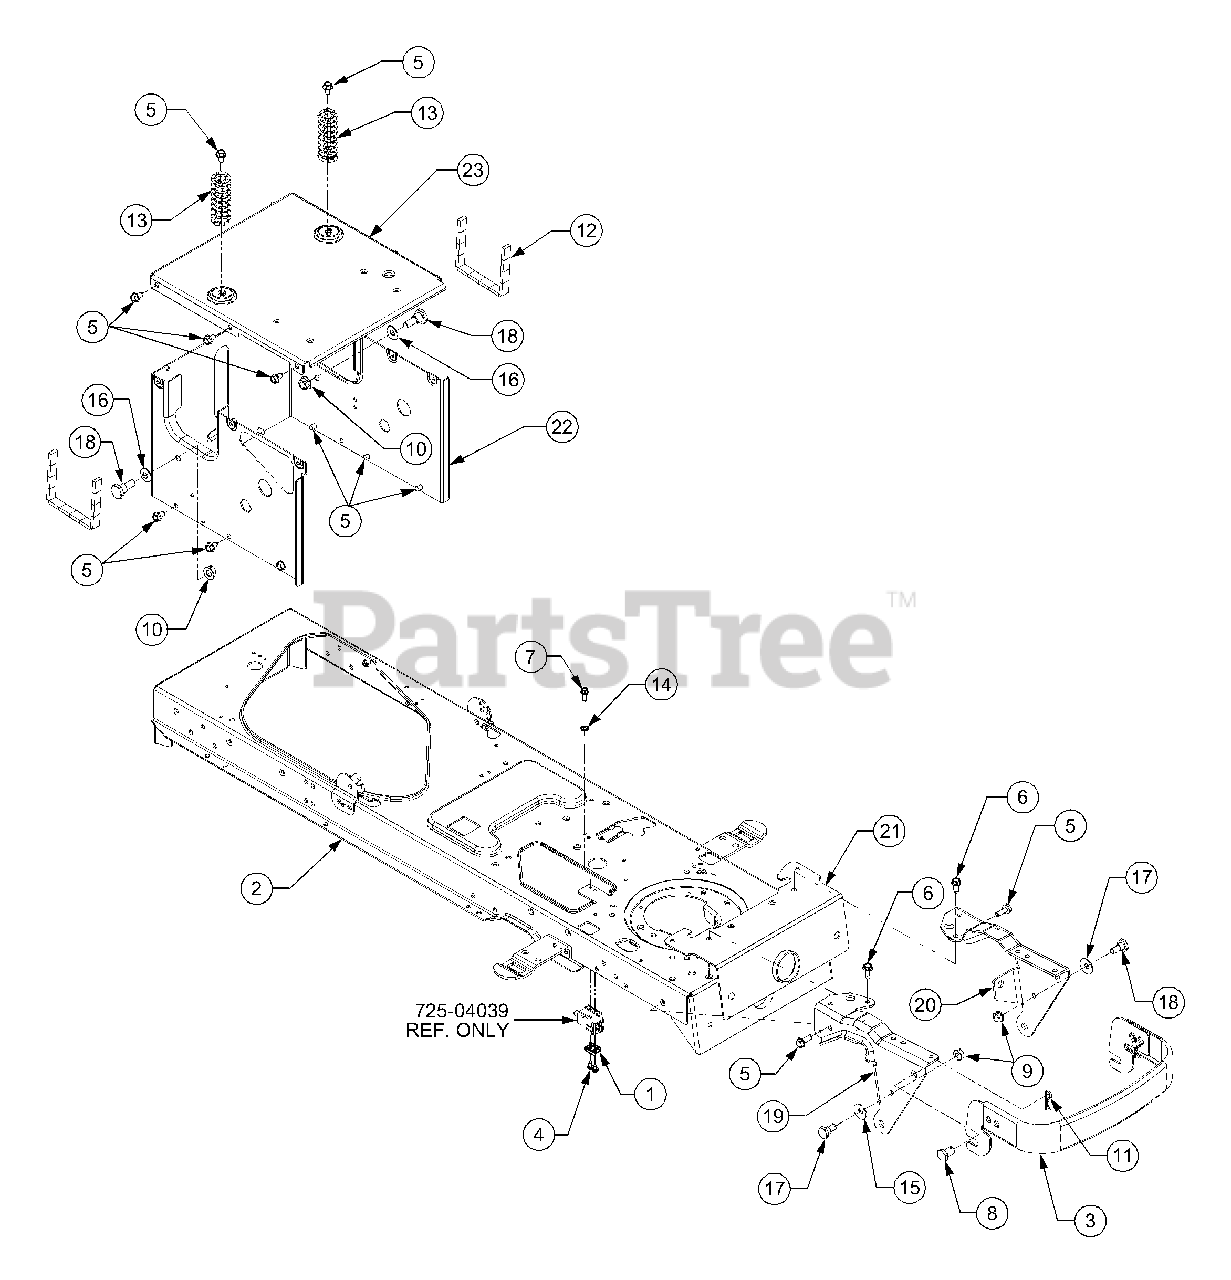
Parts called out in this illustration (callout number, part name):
1	Plate, Switch
5	Screw, Self-tapping, 5/16-18, 0.625
6	Screw, 5/16-18, 0.750
7	Screw, Hex Wash. Hd. Tapp, 1/4-20 x 0.625
8	Pin, Clevis, .50 Dia x .78 Lg
9	Nut, Flange Lock, 3/8-16
10	Nut, Flange Lock, 7/16-20
11	Pin, Click, .092 x 1.64 Lg
12	Foam Tape, .625 x .25
13	Spring, Compression, 1.28 OD x 3.125 Lg
14	Washer, Lock, Ext 1/4
15	Washer, Bell, .390 x 1.13 x .062
16	Washer, Bell .45 x 1.00 x .062
17	Shoulder Screw, 3/8-16
18	Shoulder Screw .625 x .500, 7/16-20
